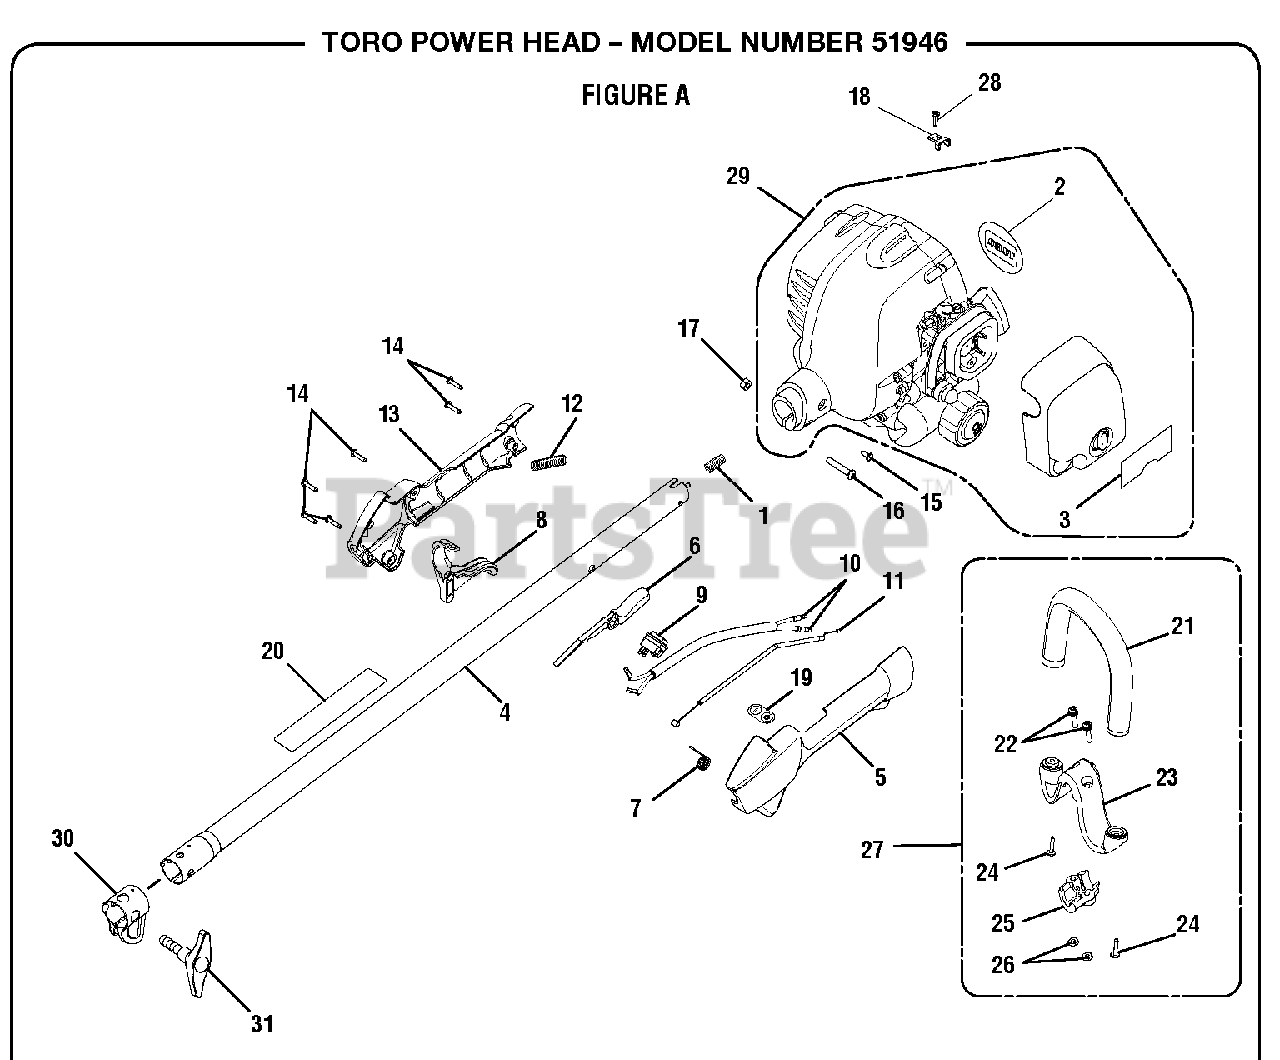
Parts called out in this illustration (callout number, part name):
1	Compression Spring
2	Logo Plate
3	Lower Start Label
4	Upper Shaft Assembly
5	Rear Handle Support
6	Lock-off Button
7	Trigger Spring
8	Trigger
9	On/Stop Switch
11	Throttle Cable
12	Corrugated Tube
13	Rear Handle Cover
14	Screw (M4 x 16 mm)
15	Screw (#8-16 x 1/2 in, Tri-Lobular)
16	Screw (M6 x 1-30 mm)
17	Hex Nut (M63 x 1)
18	Throttle Cable Clamp
19	On/Stop Label
20	Warning Label
21	Front Handle w/Grip
22	Screw (#12-24 x 1 in, Slotted Torx)
24	Screw (10-14 x 1 in)
25	Clamp
26	Hex Nut (12-24)
27	Front Handle Assembly
28	Screw (M4 x 16 mm)
29	Powerhead Assembly
30	Boom Clamp
